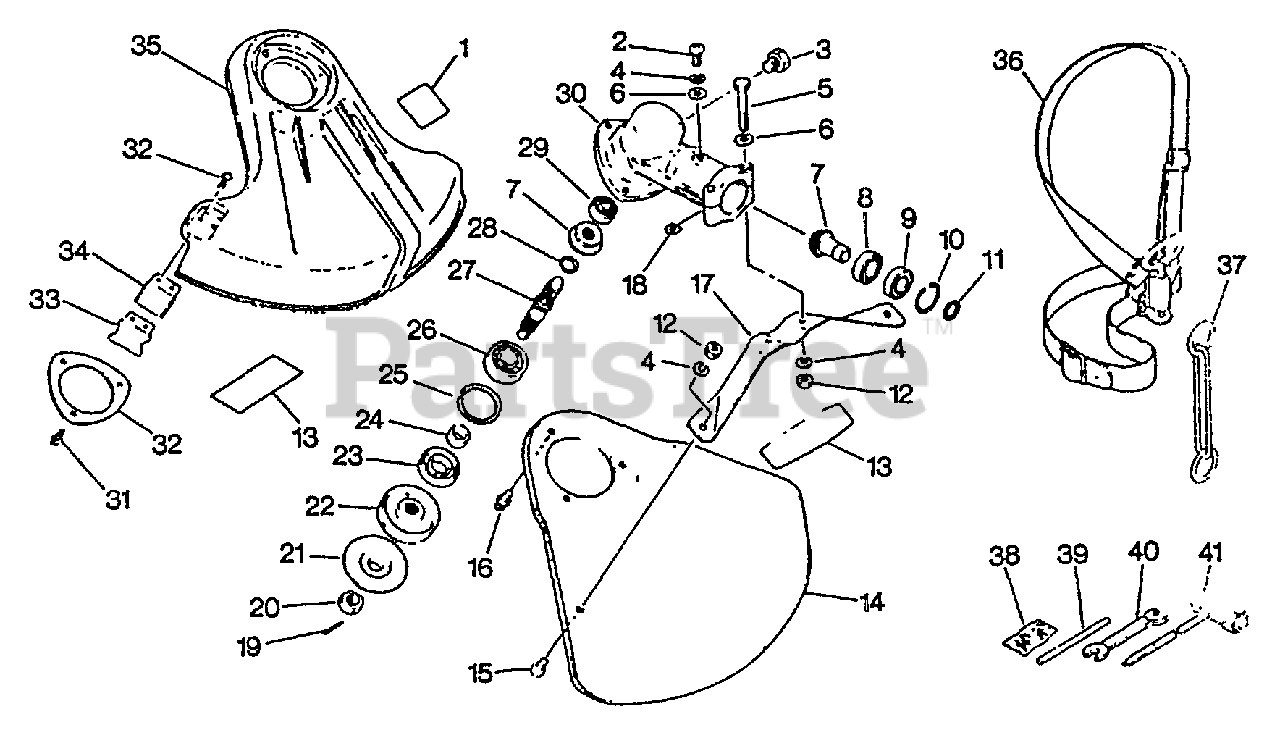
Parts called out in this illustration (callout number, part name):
1	LABEL - CAUTION
2	SCREW 5×10
3	BOLT 8×8 SP
4	WASHER, SPRING 5
5	BOLT 5×35 SP
6	WASHER, FLAT 5.5×10×0.8
7	GEAR SET
8	BEARING, BALL 6900
9	BEARING, BALL 6900Z
10	RING, SNAP Ø22
11	RING, SNAP Ø12
12	NUT M5
13	LABEL - ECHO
14	SHIELD ASSY
15	SCREW 5×8
16	SCREW 5×10
17	BRACKET, SHIELD
19	PIN, COTTER 2×22
21	PLATE, ADAPTOR - LOWER
22	PLATE, ADAPTER - UPPER
23	SEAL, OIL 22
24	SPACER 11.8×15×9
25	RING, SNAP Ø32
26	BEARING, BALL - 6201 C3
27	SHAFT, GEAR
28	RING, SNAP Ø10
29	BEARING, BALL 609
30	HOUSING, GEAR CASE
31	SCREW 5×16
32	PLATE, SHIELD Ø49.5 MM
33	PROTECTOR
34	KNIFE, TRIMMER LINE
34	CUTTER, LINE
35	SHIELD ASSY
35	DEBRIS SHIELD KIT
36	SHOULDER STRAP ASSY
37	HOOK
38	PIN, COTTER 2×22 (PKG. OF 10)
39	TOOL, LOCKING 5×120 MM
40	SPANNER 8×10
41	T-WRENCH 17x-19 L200
